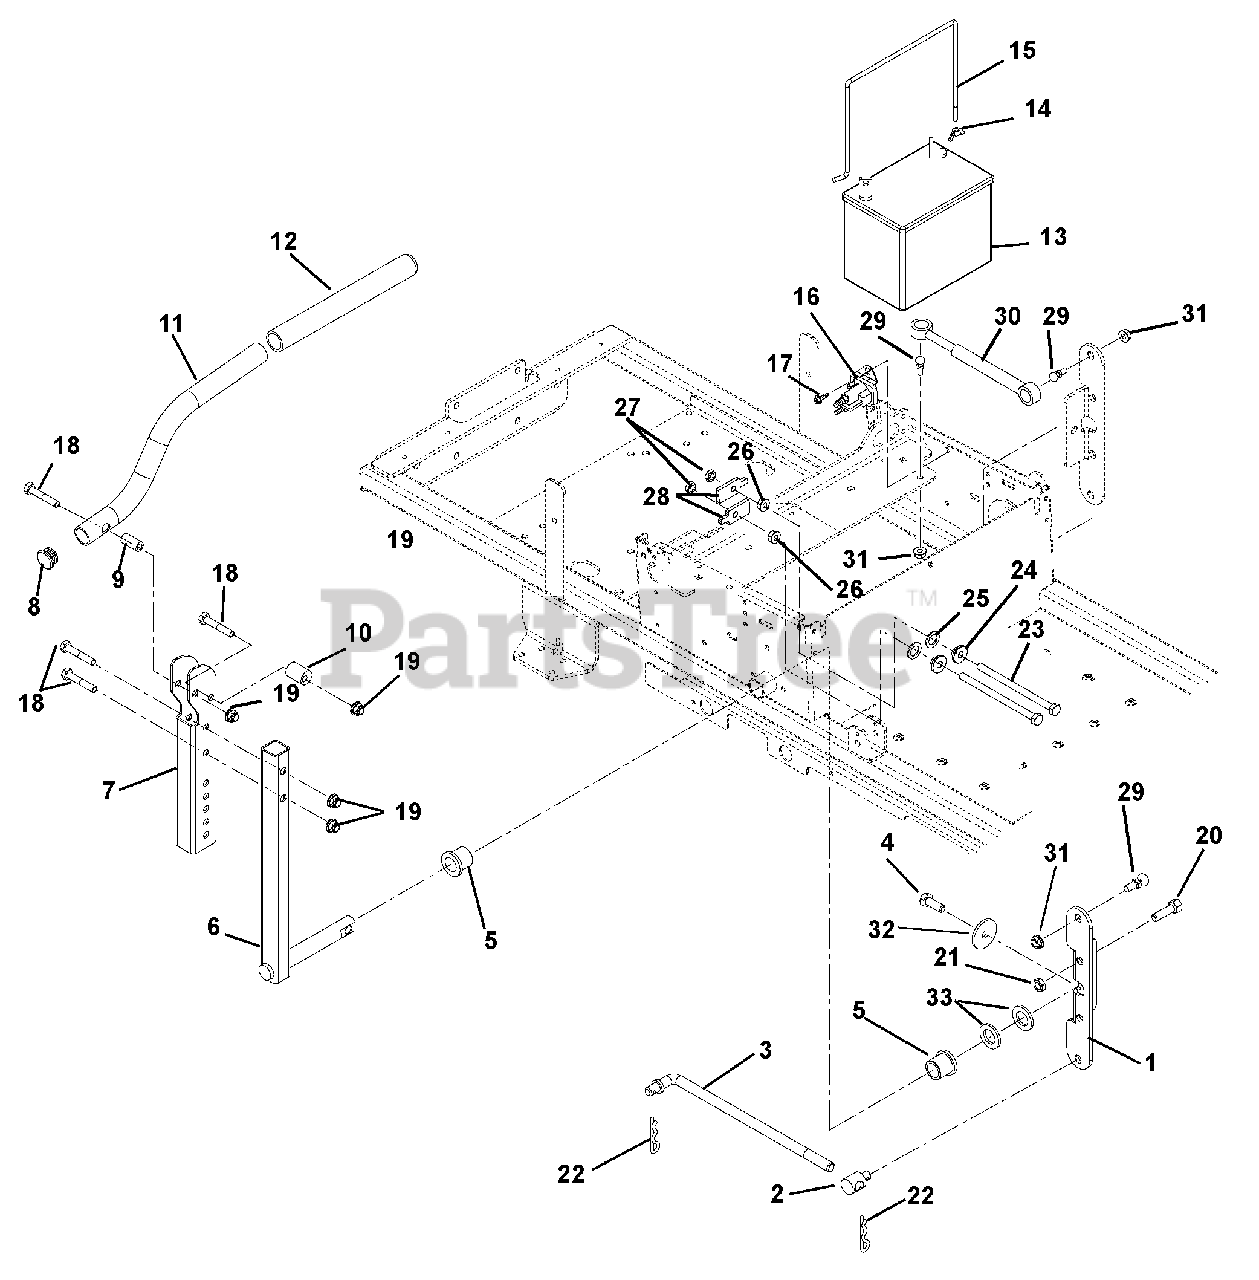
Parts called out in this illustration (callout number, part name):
1	Link, Control
2	Pivot, Rod
3	Link, Wireform
4	Bolt, .38-16 x 1.00
5	Bushing, 1.00 x .75 x 1.00
6	Weldment, Control Arm
7	Channel, Upper Handlebar
8	Caplug, Handlebar
9	Bushing, Spacer .330 x .505 / .500 x 1.01
10	Eccentric
11	Handlebar
12	Grip, Handlebar
13	Battery, Exide Sealed Maintenance Free U1-250 (Purchase replacement locally)
14	Nut, Lock Wing .250-20
15	Battery Rod
16	Solenoid
17	Screw, Tap .250-20 x .37
18	Bolt, Hex .31-18 x 1.75 Grade 5
19	Nut, 031-18 Flange Nyloc
20	Bolt, Hex .38-16 x 1.25 Grade 5
21	Nut, Hex Jam .375-16
22	Pin, Hair Internal .08 x .18 x 1.18
23	Bolt, Hex 5/16-18 x 5 Grade 2
24	Bushing, Flange .312 x .500 x .344 x .880
25	Washer, Flat Steel .52 x .827 x .062
26	Nut, Spin Lock-Flange .312-18
27	Nut, Jam .312-18
28	Tab, Stop
29	Stud, Ball
30	Damper, Control
31	Nut, Locking Top Flange .31-18
32	Washer, Flat, Steel .39 x 1.5 x .125
33	Washer, Flat, Steel .755 x 1.25 x .125
